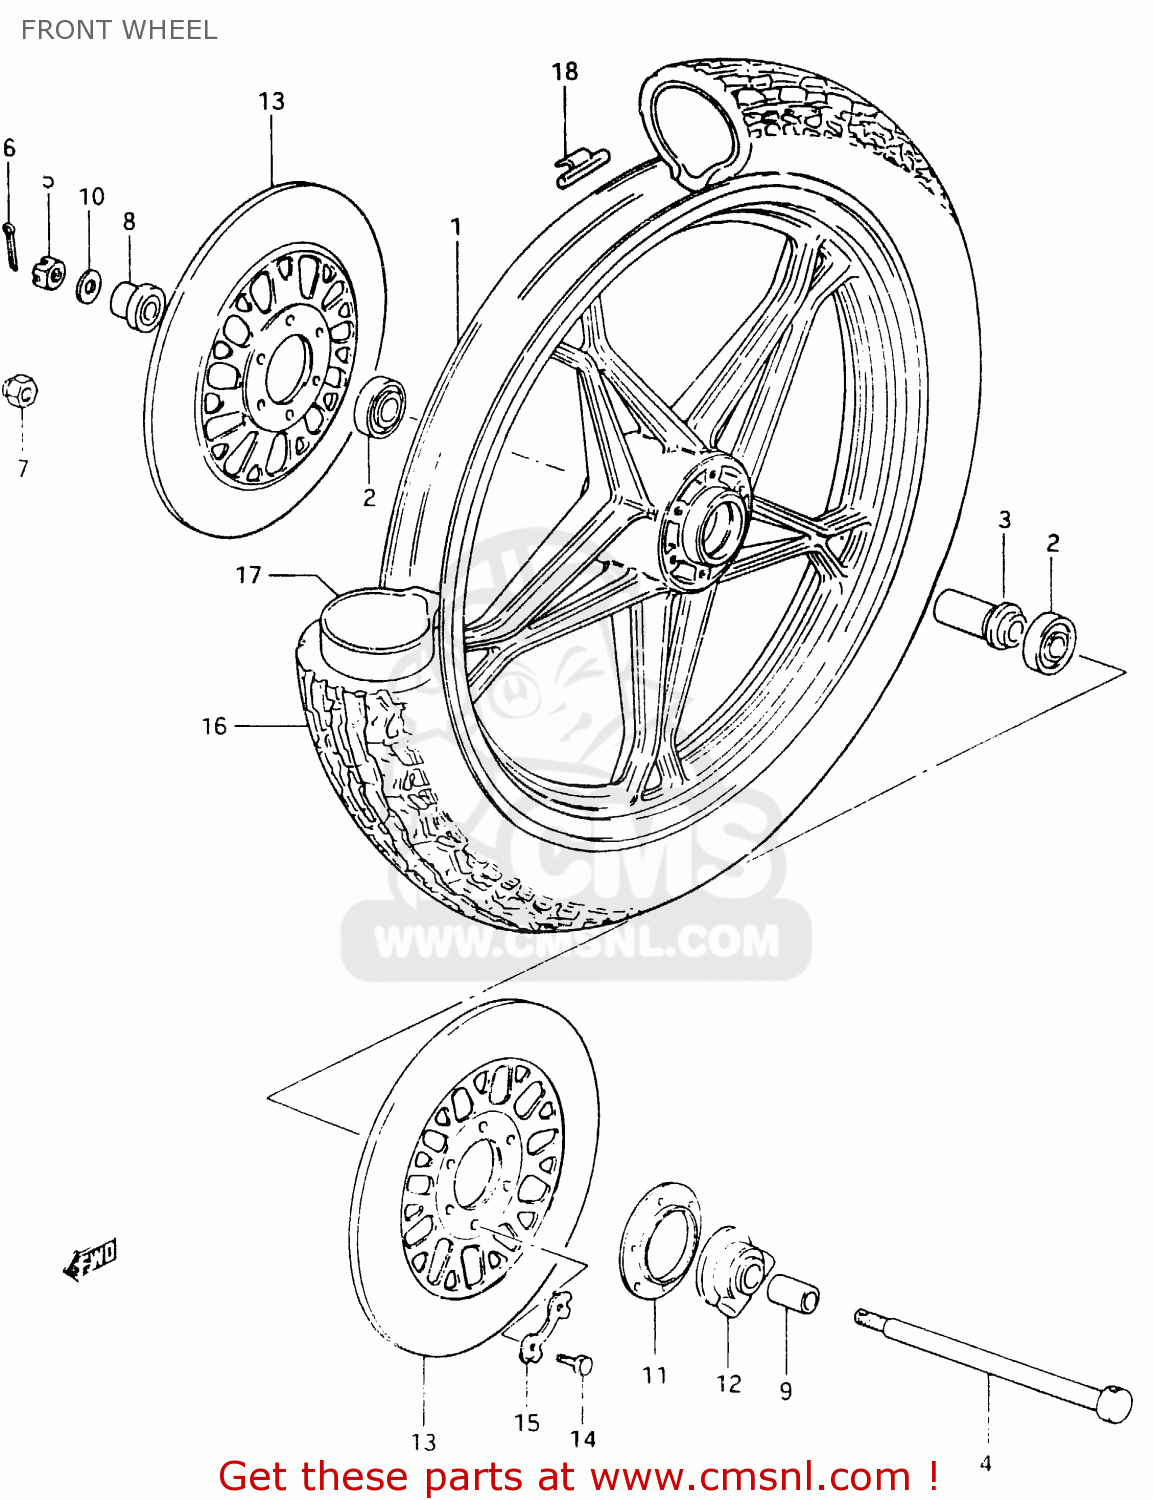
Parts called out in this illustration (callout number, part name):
1	WHEEL, FRONT (19X1.85) (GRAY)
2	BEARING
3	SPACER,FR HUB BEARING
4	AXLE,FRONT
5	NUT 12MM
6	COTTER PIN
7	NUT
8	SPACER,FR HUB BEARING,R
9	SPACER(15X22X30)
10	WASHER
11	DUST SEAL,SPEEDOMETER GEAR BOX
12	BOX ASSEMBLY,SPEEDOMETER GEAR
13	DISK, FRONT BRAKE
14	BOLT(8X25)
15	WASHER
16	TIRE (3.25S19)
17	TUBE,INNER
18	BALANCER,WHEEL
